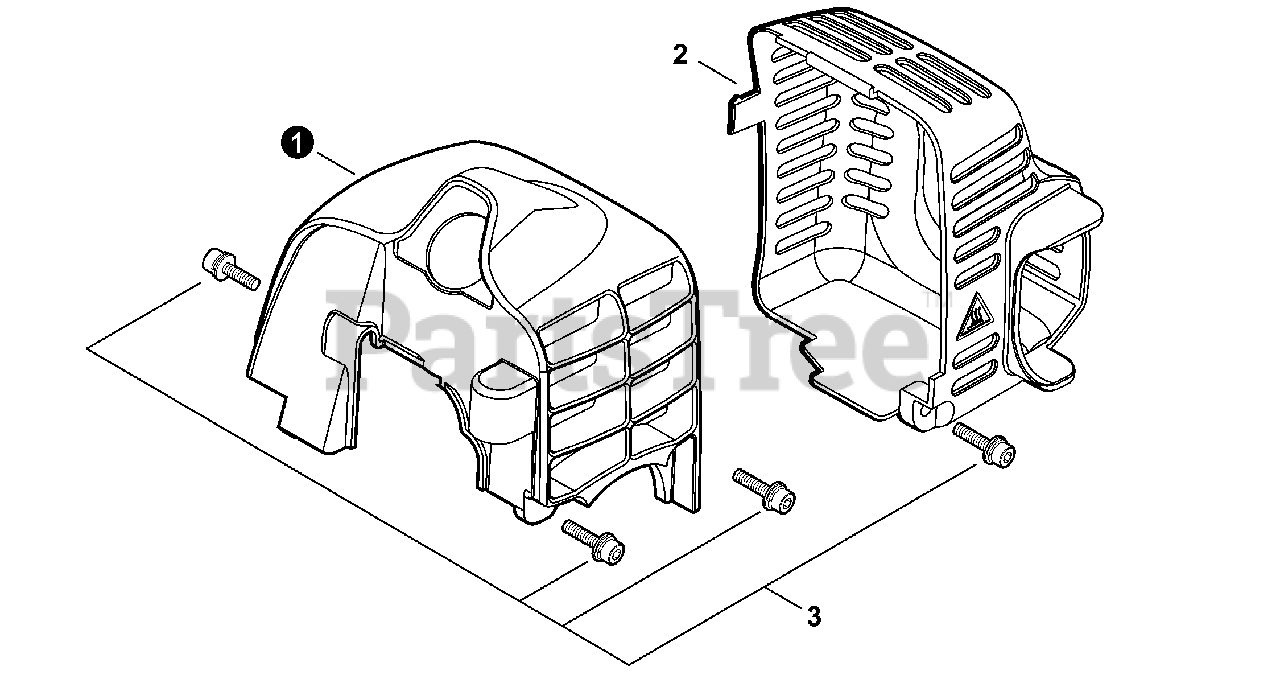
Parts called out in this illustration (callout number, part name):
1	COVER, ENGINE
2	COVER, MUFFLER
3	BOLT, ADHESIVE M5×20
